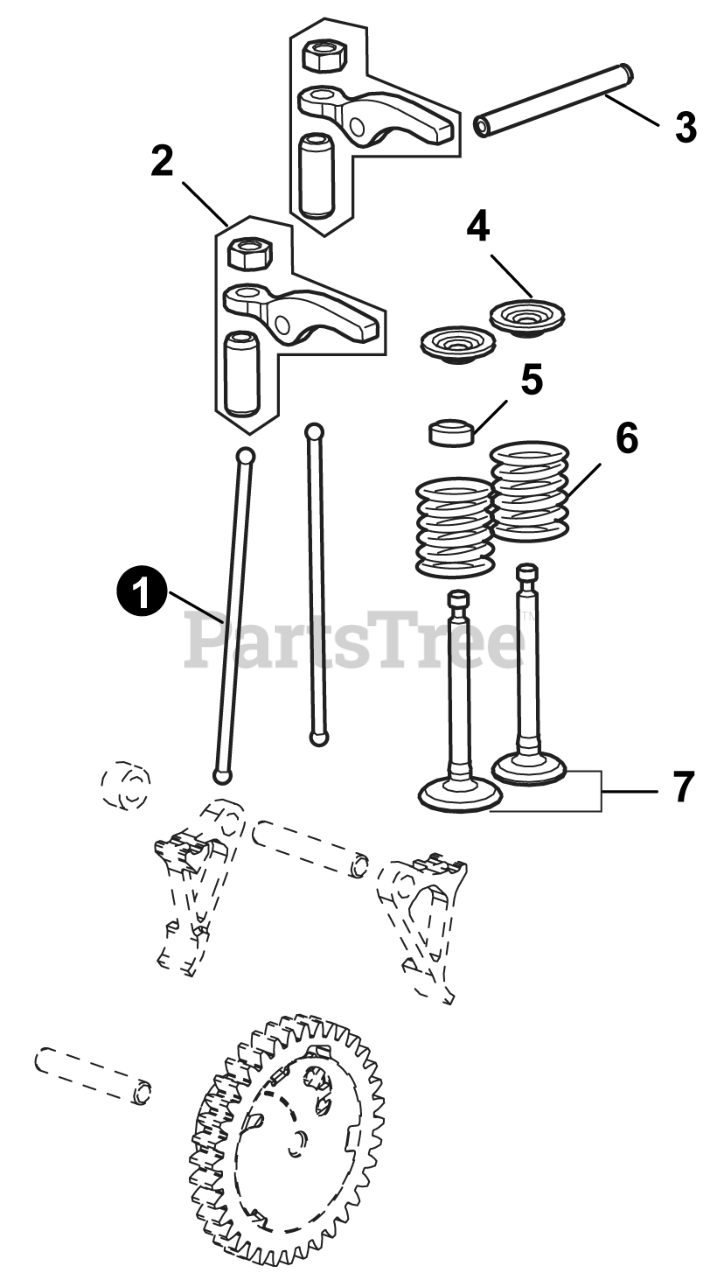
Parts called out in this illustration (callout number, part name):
1	ROD, PUSH
2	ARM, ROCKER
3	SHAFT, ROCKER
4	SEAT, VALVE SPRING
5	SEAL, GUIDE
6	SPRING, VALVE
7	VALVE KIT, INTAKE/EXHAUST
